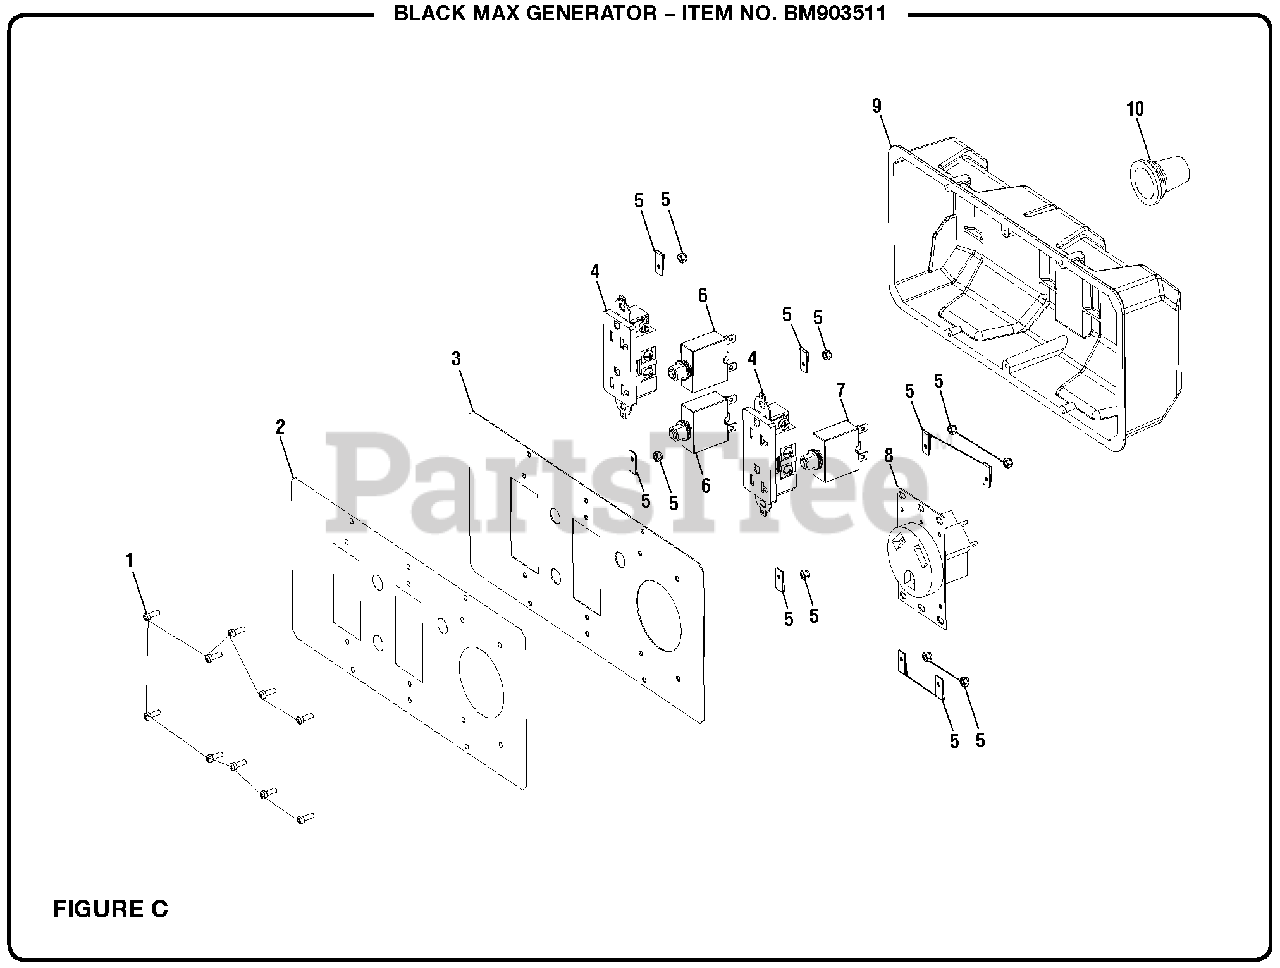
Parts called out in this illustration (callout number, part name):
1	Screw (#6-20 x 9.65 mm, Pan Hd.)
2	Outlet Panel Label
3	Electrical Panel
4	120V Duplex Receptacle
5	Hex Nut (#6-32)
6	Circuit Breaker (20A)
7	Circuit Breaker (30A)
8	120V/30A Recepticle (Twist Lock)
9	Control Box Housing
10	Rubber Boot
